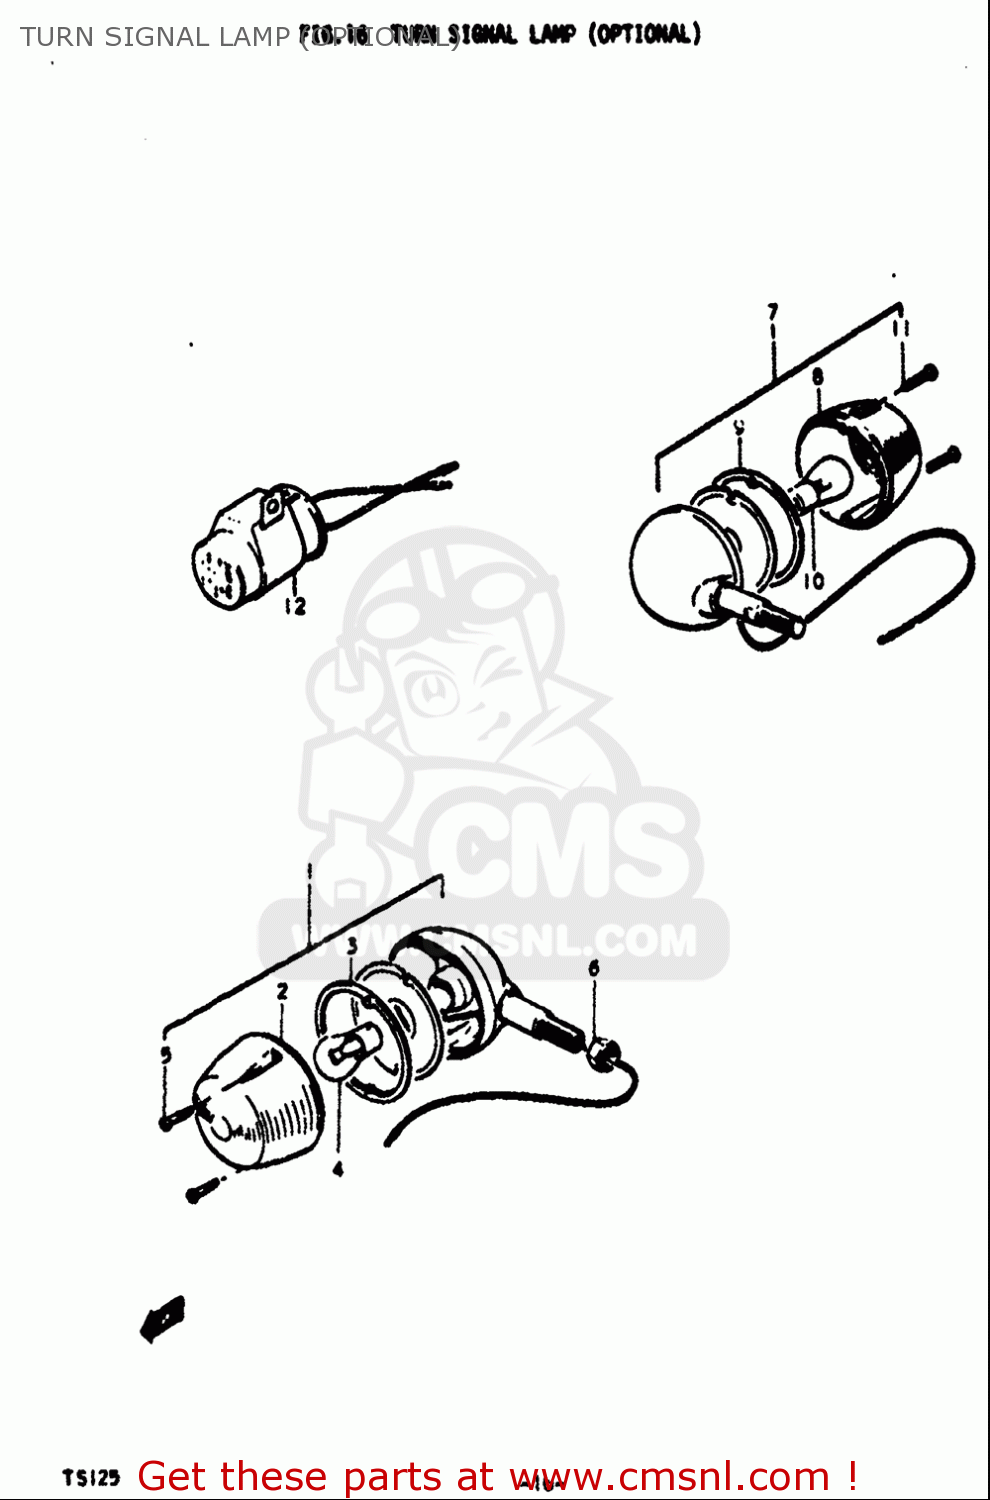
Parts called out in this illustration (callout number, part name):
2	LENS,TURNSIGNAL
3	GASKET,TURNSIGNAL LENS (NAS)
4	BULB(6V17W,STANLEY,A4513A)
5	SCREW
6	NUT
8	LENS,RR TURNSIGNAL LAMP
9	GASKET,TURNSIGNAL LENS (NAS)
10	BULB(6V17W,STANLEY,A4513A)
11	SCREW
12	RELAY ASSY,TURNSIGNAL
